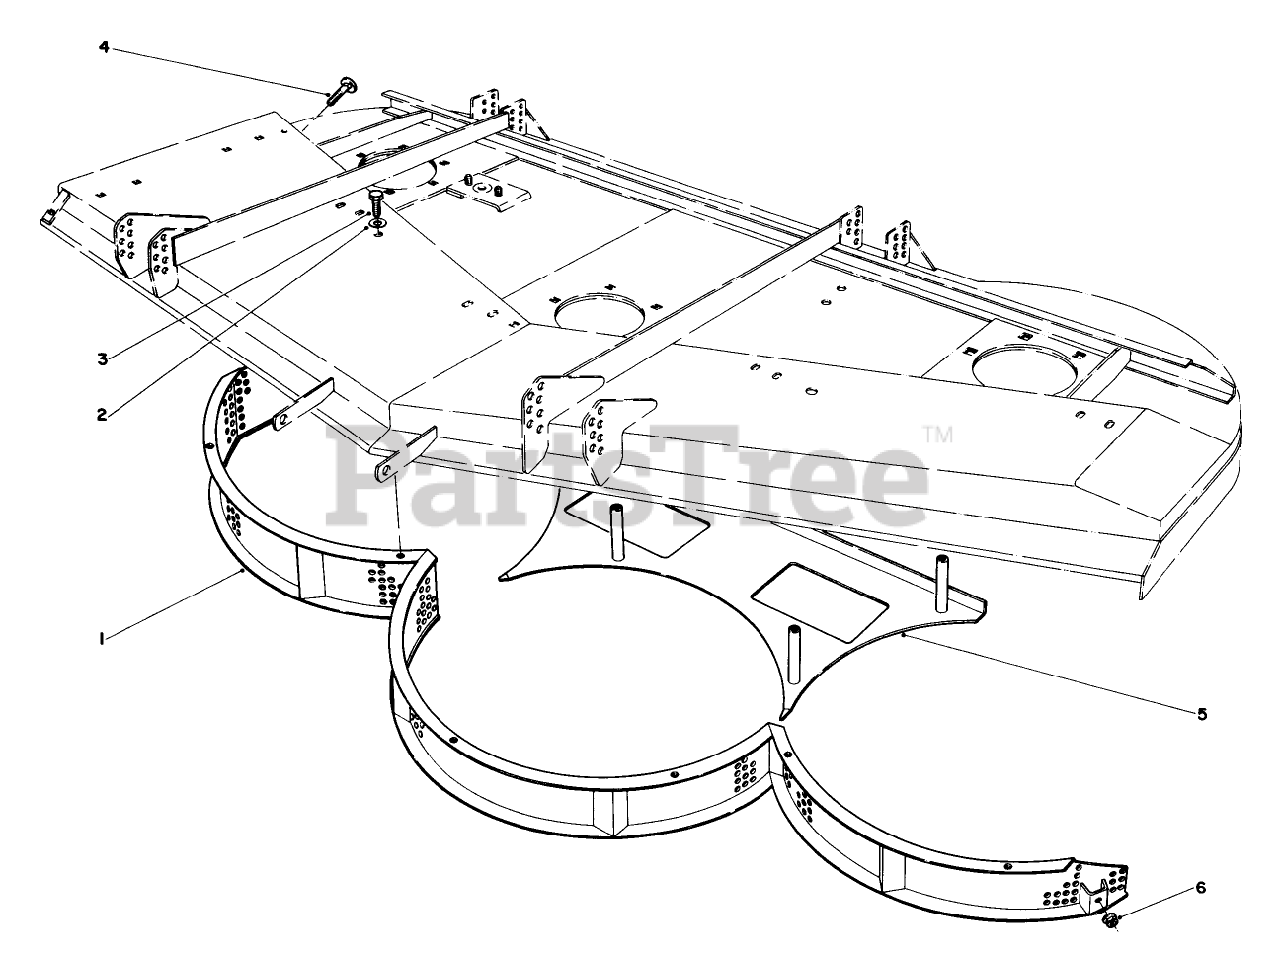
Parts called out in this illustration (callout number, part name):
2	WASHER-LOCK
3	SCREW-HH
4	BOLT-CARR
6	NUT-HHF, WHIZ
